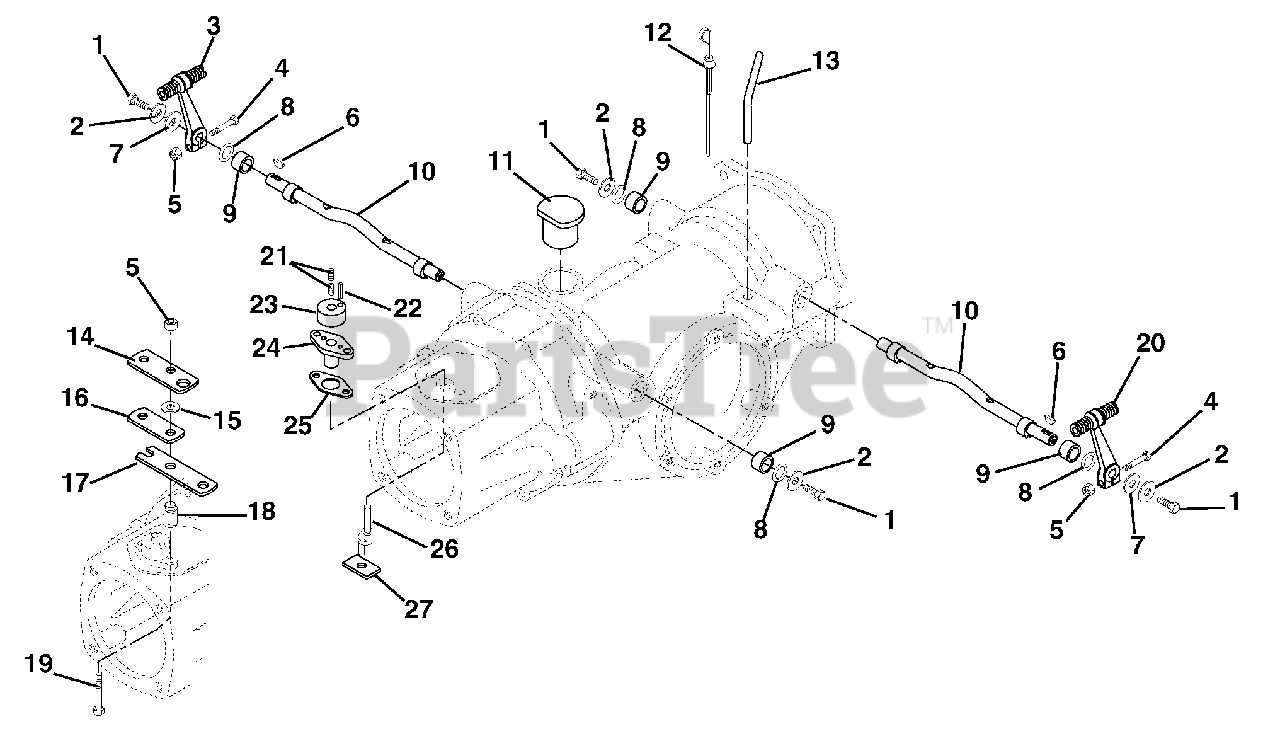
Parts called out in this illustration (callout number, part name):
1	Bolt-Hex .25-20 x .50 Grade 5
2	Washer-Flat-Steel .281 x 1.250 x .048
3	Assembly-Forward Reverse Lever
4	Bolt-Hex .31-18 x 2.00 Grade 5
5	Nut-Locking-Center .312-18 Grade 2
6	Key-Woodruff .13 x .63
7	Washer-Flat .812 x 1.500 x .139
8	O-Ring .750 x 1.0
9	Bushing-Sleeve .749 x 1.00 x .625
10	Shaft-Actuating
11	Plug-Oil Filler
12	Assembly-Dip Stick
13	Guide-Dip Stick
14	Bracket-PTO Switch
15	Washer-Flat-Steel .344 x .688 x .065
16	Spacer-Strap
17	Arm-Shifter
18	Bushing-Flange .344 x .562 x .866
19	Bolt-Hex .31-18 x 2.50 Grade 5
20	Assembly-Hi-Lo Lever
21	Screw-Set .38-16 x .25
22	Pin-Roll .250 x .75
23	Body-Shipper Shaft
24	Shaft-Shipper
24	Guard-Shipper Shaft
25	Gasket-Shipper Shaft
26	Shaft-Shipper
27	Block-Trunnion
